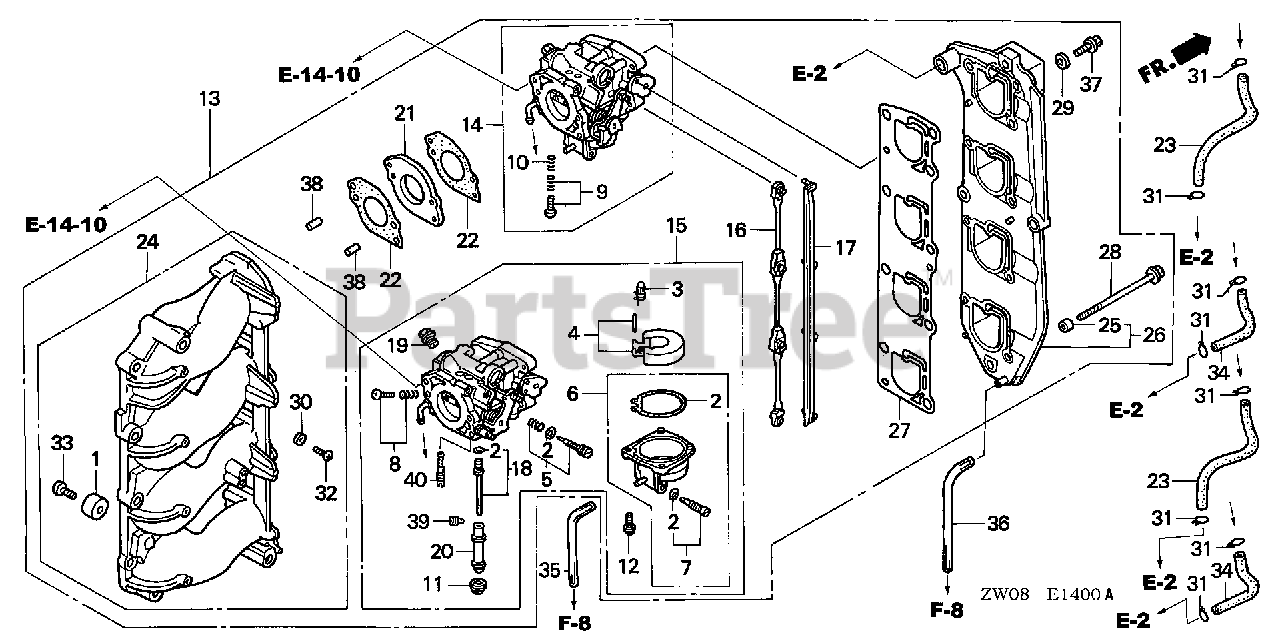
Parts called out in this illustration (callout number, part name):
1	METAL, ANODE
2	GASKET SET
3	VALVE SET, FLOAT
4	FLOAT SET
5	SCREW SET (CARBURETOR NO.)
6	CHAMBER SET, FLOAT
7	SCREW SET, DRAIN (CARBURETOR NO.)
7	SCREW SET, DRAIN
10	SPRING, COMPRESSION COIL
11	SCREW, PLUG
12	SCREW-WASHER
13	CARBURETOR ASSY. (BG40D B) *NH8* (DARK GRAY)
14	CARBURETOR ASSY. (#1 #2 #3)
15	CARBURETOR ASSY. (#4)
16	LEVER, LINK
17	LINK, CHOKE
18	JET SET (#40)
19	BOLT, HOLDING
20	NOZZLE, MAIN
21	INSULATOR, CARBURETOR
22	GASKET, CARBURETOR
23	TUBE A, FUEL
24	MANIFOLD ASSY., IN. *NH8* (DARK GRAY)
25	COLLAR, DISTANCE (6.5X11X7.5)
26	PLATE, MUFFLER (CARBURETOR NO.)
27	GASKET, MUFFLER PLATE
28	BOLT, FLANGE (6X106)
29	WASHER, PLAIN (6MM)
30	WASHER, SEALING (5MM)
31	CLIP, TUBE (B10)
32	SCREW, PAN (5X10)
33	SCREW, PAN (6X18)
34	BULK HOSE, FUEL (5.5X3000) (Honda Code 5338587). (5.5X150)
35	BULK HOSE, VINYL (3.5X6.5X8000) (9500(95003-05001-60M) (CARBURETOR NO.)
37	BOLT, FLANGE (6X20)
38	ROLLER (6X15)
39	JET, MAIN (#130)
39	JET, MAIN (#132)
39	JET, MAIN (#128)
40	JET, SLOW (#52)
